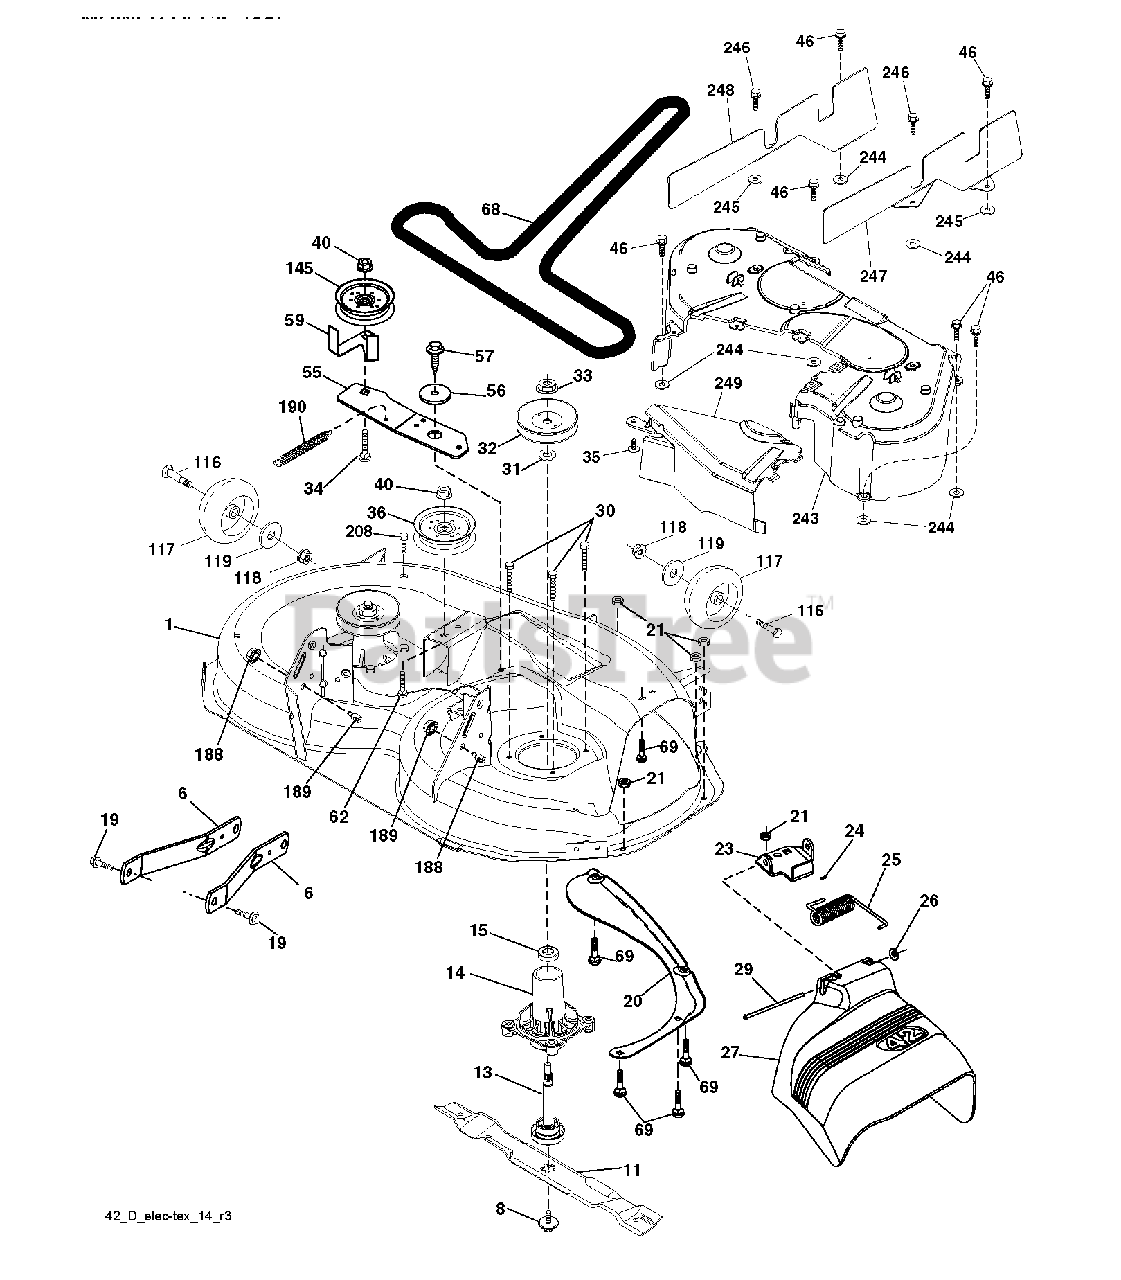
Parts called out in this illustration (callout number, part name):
1	DECK.WELDMENT.42"
6	ARM.SUSPENSION.MOWER.R
8	BOLT.WASHER.ASM.7/16-2
11	42" HI-LIFT BLADE
13	SHAFT.ASM.MDRL.N/GREASE.38
14	HOUSING MANDREL
19	BOLT.SHOULDER
20	BAFFLE.VORTEX
21	LOCKNUT
23	BRKT.DEFLECTOR.38"2005+
24	CAP-SLEEVE LT
25	SPRING.TORSION.DEFLECT
26	NUT PUSH M
29	ROD.HINGE
30	SCREW, WASHER HEAD
31	WASHER.SPACER.MANDREL
32	PULLEY/MANDREL
33	NUT.FLANGE.LOCK.TOP
34	BOLT
35	FASTENER.XMAS.TREE
36	PULLEY.IDLER.2006
40	NUT LOCK FLG 3/8-16 UNC
46	SCREW.1/4-20X5/8
55	IDLER.ARM
56	SPACER.RETAINER
57	SCREW 3/8-16X1
59	GUARD, BELT
62	BOLT.3/8-16X1.50
68	BELT V SECONDARY
69	BOLT
117	WHEEL.GAGE.HALF.SPOKED
118	LOCKNUT
119	WASHER
145	PULLEY.IDLER.48"PRIMARY
188	STUD.FASTNER.W/ANTI-ROTATE
189	NUT LOCK HEX FLANGE 5/16-18
190	SPRING.MOWER.DRIVE.ELECTRIC
208	SCREW 3/8-16X1/2
244	PALNUT 1/4
246	SCREW, 5/16-18 X 1/2
